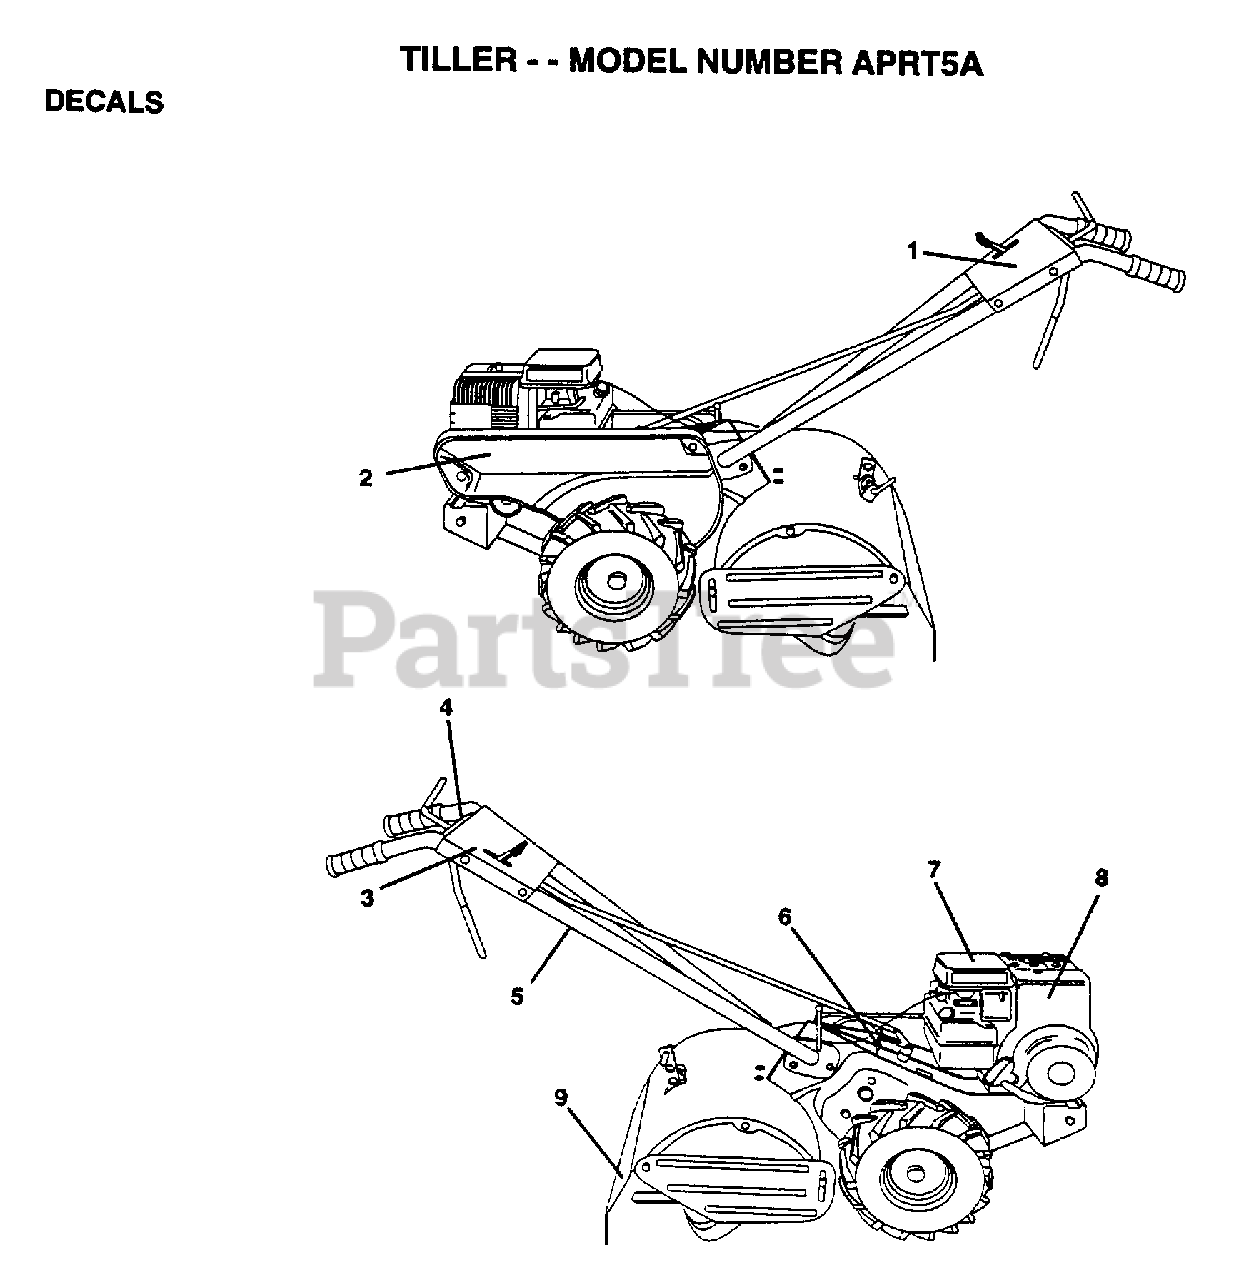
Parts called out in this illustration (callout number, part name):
1	DECAL.CNTRL.PNL.A
2	DECAL.GUARD.BELT
3	DECAL, PANEL CONTROL
5	DECAL TI
7	DECAL TI
8	DECAL, BRIGGS & STRATTON
